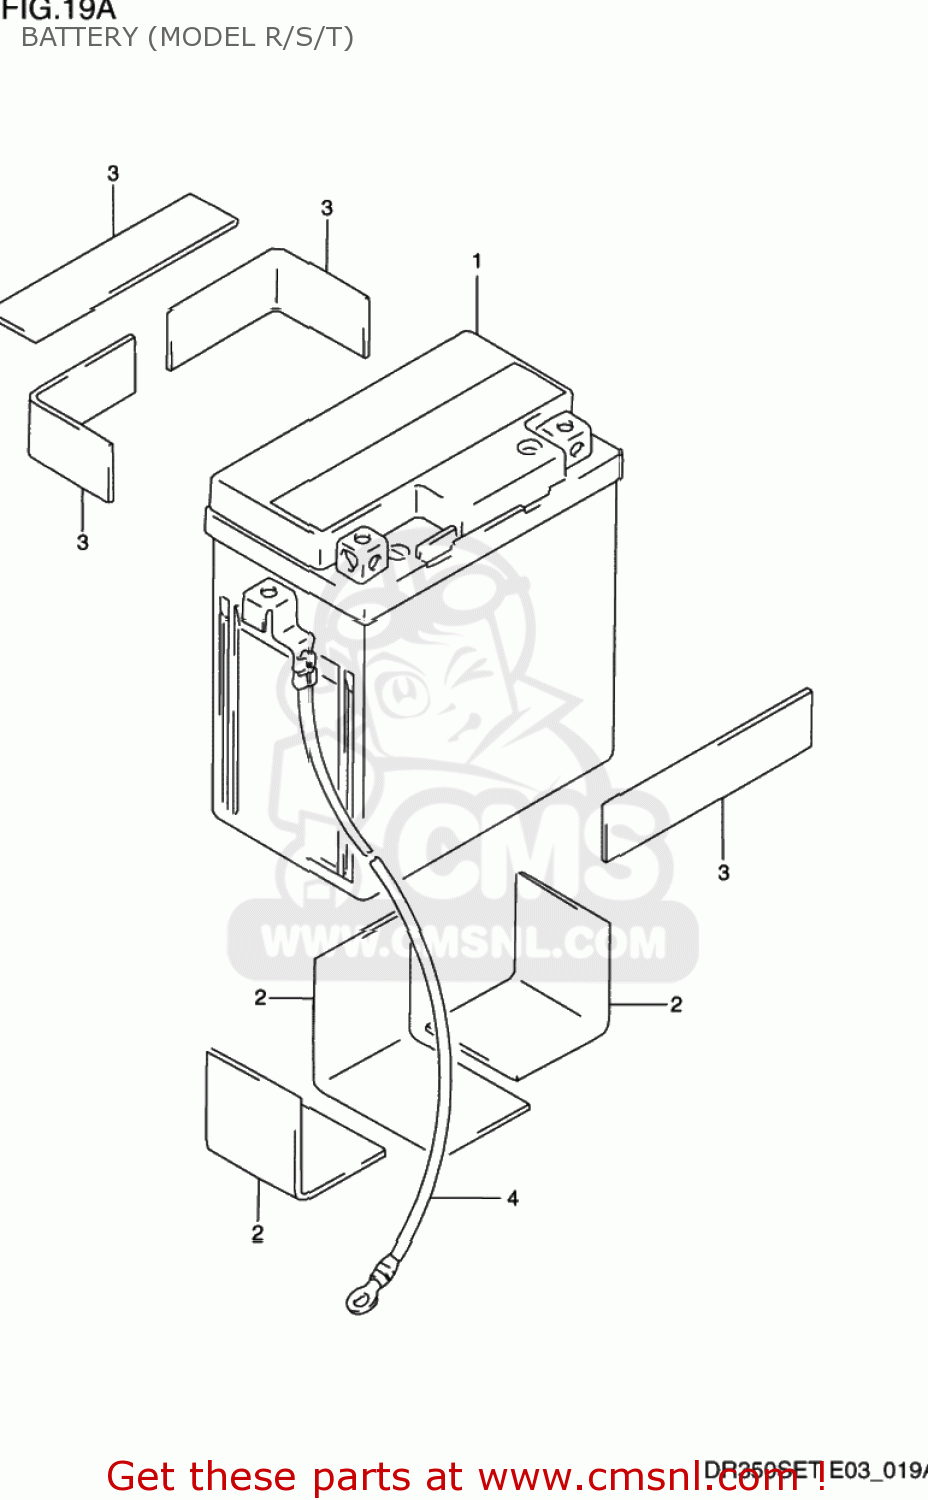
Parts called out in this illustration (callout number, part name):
1	BATTERY ASSEMBLY (12V) YTX
2	PROTECTOR(170X95X3.0)
3	PROTECTOR(170X95X3.0)
4	WIRE,BATTERY MINUS LEAD
